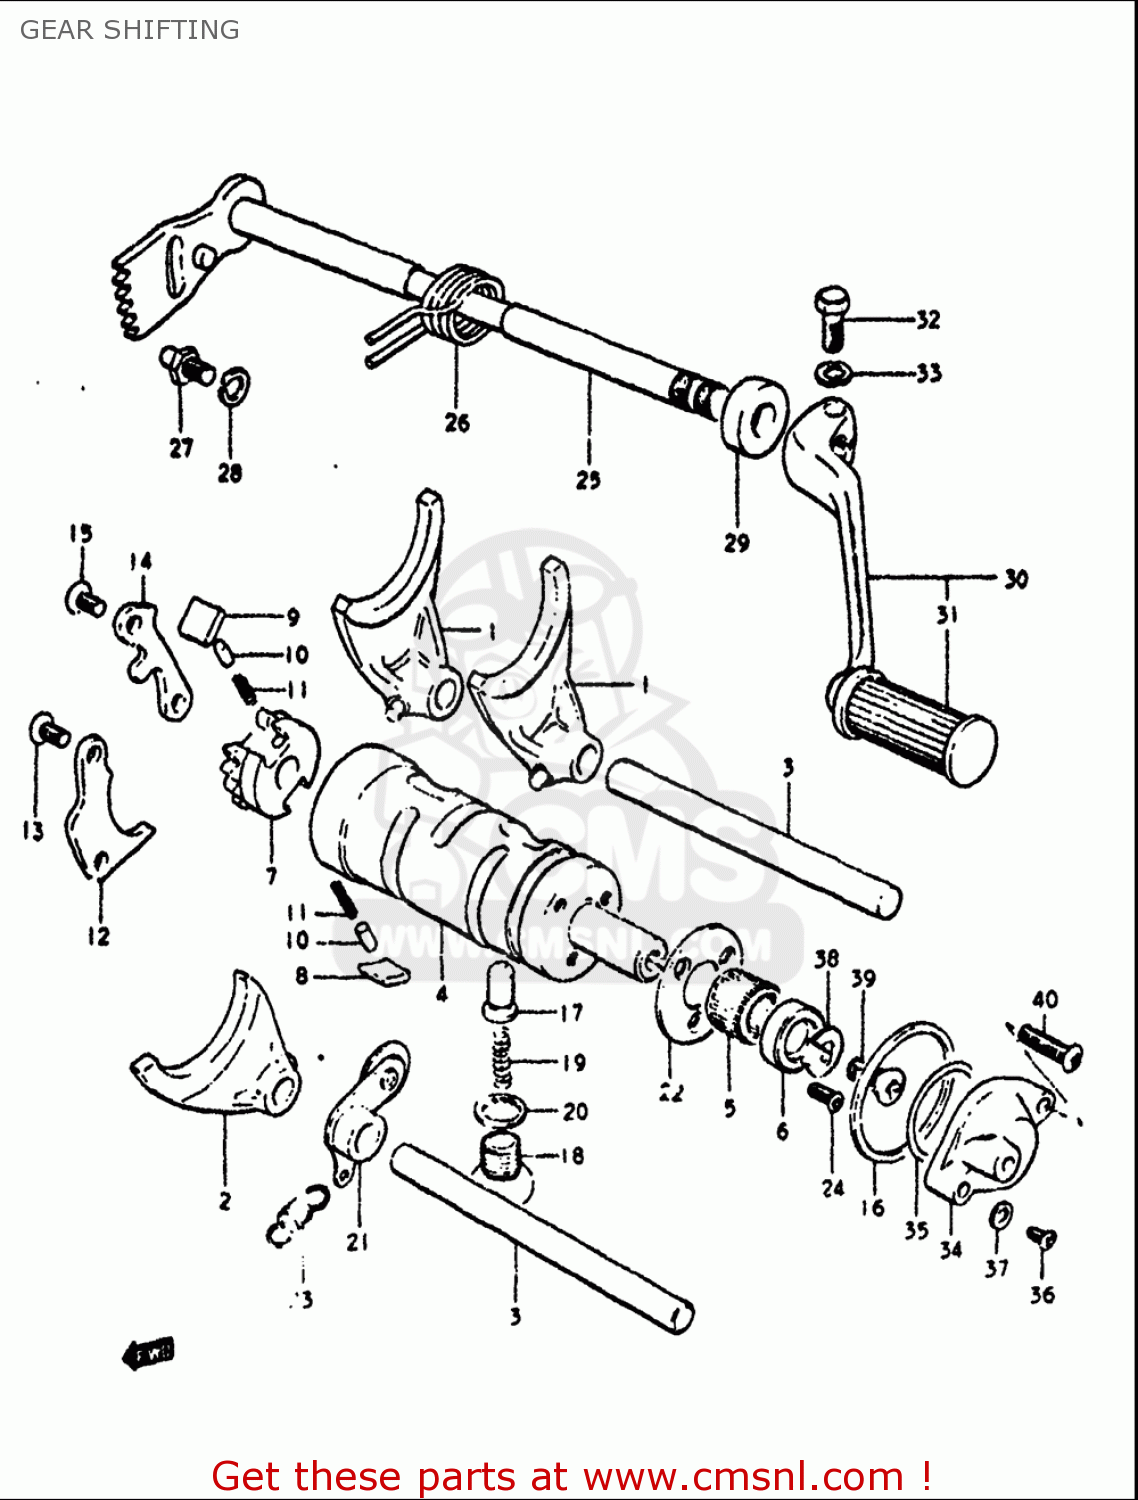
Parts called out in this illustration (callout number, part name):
3	SHAFT,GEAR SHIFT FORK
5	BEARING(16X22X12)
6	SEAL,OIL(16X24X7)
7	GEAR,GEAR SHIFT CAM DRIVEN
8	PAWL,GEAR SHIFT NO.1
9	PAWL,GEAR SHIFT NO.2
10	PIN(5X8)
11	SPRING
12	LIFTER,GEAR SHIFT PAWL
13	SCREW
14	GUIDE,GEAR SHIFT
15	SCREW
16	WASHER(40X45X1)
17	STOPPER,GEAR SHIFT CAM NO.2
18	HOLDER,GEAR SHIFT CAM STOP SPR
19	SPRING
20	GASKET(14X19.2X2) (NAS)
23	SPRING
24	SCREW
26	SPRING
27	STOPPER,GEAR SHIFT ARM
28	WASHER,LOCK
29	SEAL,OIL (12X22X9)
31	RUBBER,GEAR SHIFT PEDAL
32	BOLT
33	WASHER,LOCK
34	BODY,GEAR SHIFT SWITCH
35	O RING(D:1.9,ID:27.7)
36	SCREW
37	WASHER
38	CONTACT,GEAR SHIFT SWITCH
39	SCREW
40	SCREW
